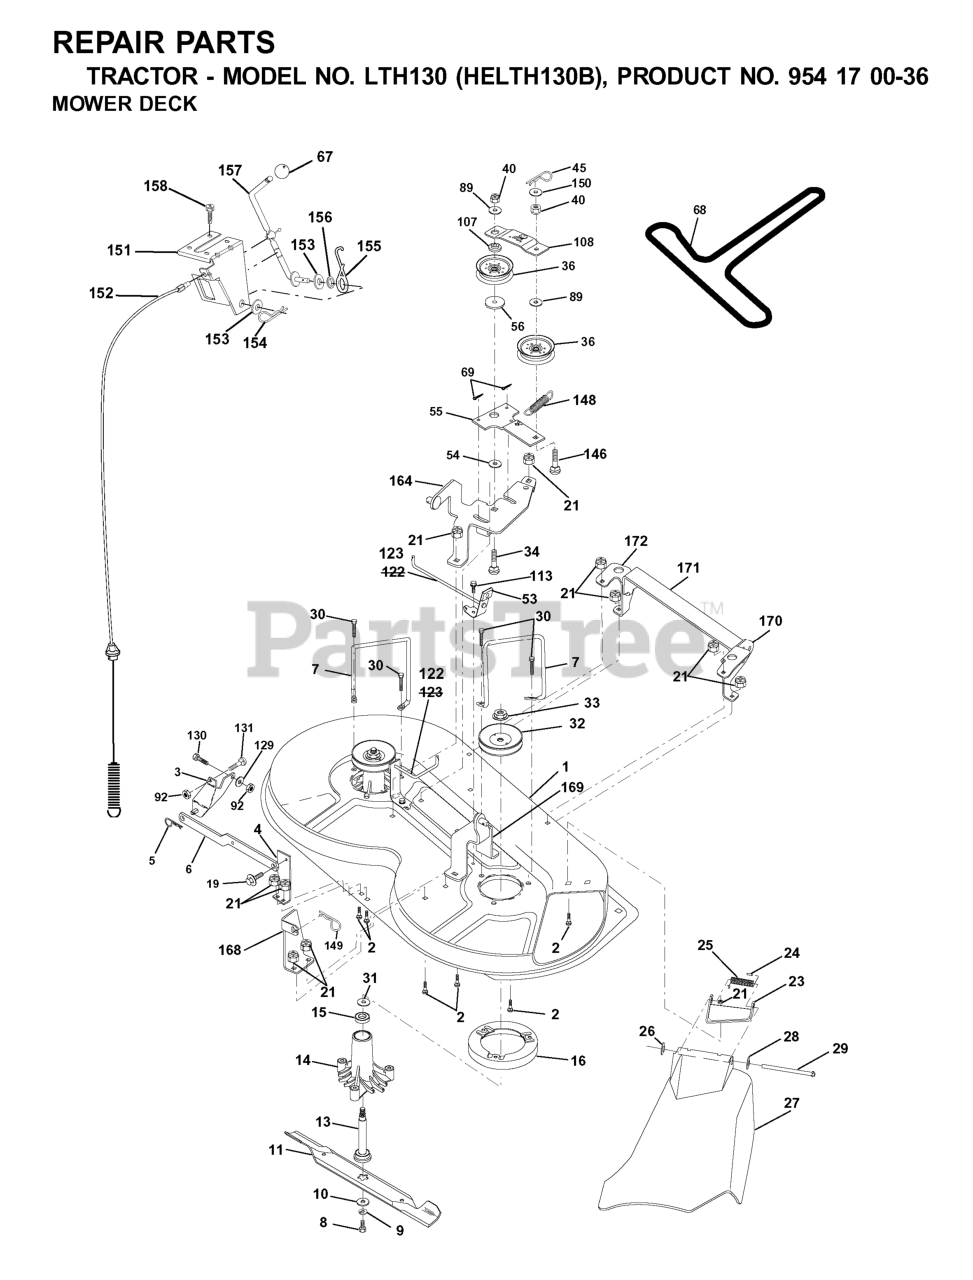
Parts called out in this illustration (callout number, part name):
2	RP BOLT 5/16-18 X3/4 ZN/YEL GR
3	BRKT ASM SWAY BAR
5	RETAINER-SPRNG RB
6	REAR SUSP ARM
8	BLADE BOLT
9	LOCKWASHER
10	WASHER.BLADE
11	BLADE, HI-LIFT 36" PREMIUM
13	SHAFT ASM VENT
14	HOUSING.MANDREL.VENTED (MACHD)
16	STRIPPER.MANDREL.ROUND.BLACK
19	BOLT SHD 5/16-18
21	LOCKNUT
23	BRACKET ASM DEFLECTOR
24	CAP-SLEEVE LT
25	SPRING TORSION
26	NUT PUSH M
27	CONSOLE.STLT.5SP.BLK
28	Washer 11/32 x 5/8 x 16 Ga SD
29	HINGE ROD
30	SCREW THDROL ROLLING WASHER HD
31	WASHER
32	PULLEY, MANDREL
33	NUT
36	FLAT IDLER PULLEY
45	RETAINER M
53	BRAKE ASSEMBLY
54	HARDENED WASHER
56	SPACER.RETAINER.MOWER
67	KNOB T (3/8 HOLE)
69	COTTER PIN
89	WASHER GT
92	NUT
107	SPACER.IDLER.ARM
108	STIFFENER.IDLER.ARM
113	Screw 5/16-18 x 1/2 Hex, Self Tapping 5/16-18 x 1/2
129	WASHER
131	BOLT D
146	BOLT, CARRIAGE IDLER
148	IDLER RETURN SPRING
149	SPRING.RETAINER.YELLOW.ZINC
151	BRACKET.CLUTCH.CABLE
153	WASHER FLAT 3/8"
154	SPRING RETAINER
155	SPRING RETENTION LEVER
156	SPACER.CLUTCH.CABLE
157	ROD CLUTCH CABLE 3/8"
158	SCREW LT
171	BRACE.SUPT.SUSP.FRT.CRD
